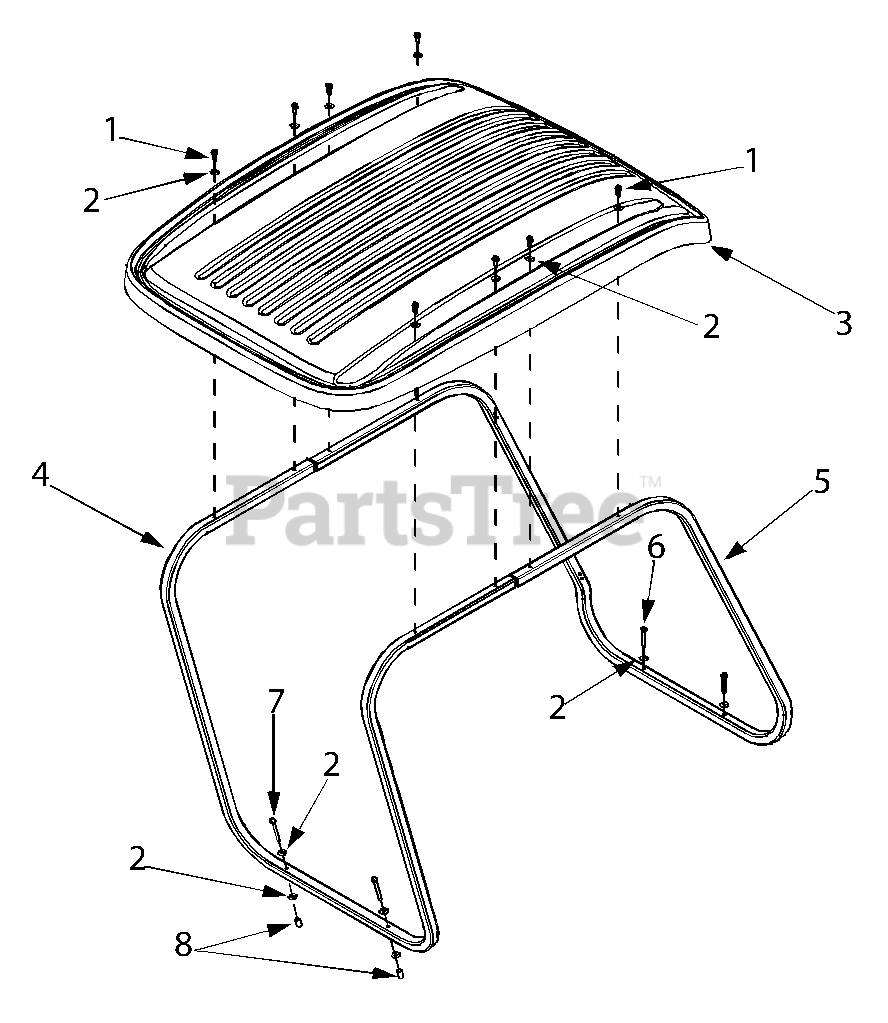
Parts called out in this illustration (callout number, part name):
1	Hex Washer Screw 1/4-20 x .75
2	Flat Washer .260 ID x .720 OD
3	Canopy Panel
4	Rear Canopy Frame
5	Front Canopy Frame
6	Hex Cap Screw 1/4-20 x 1.75
7	Hex Cap Screw 1/4-20 x 2.5
8	Spacer .280 ID x .437 OD x .850 Lg
